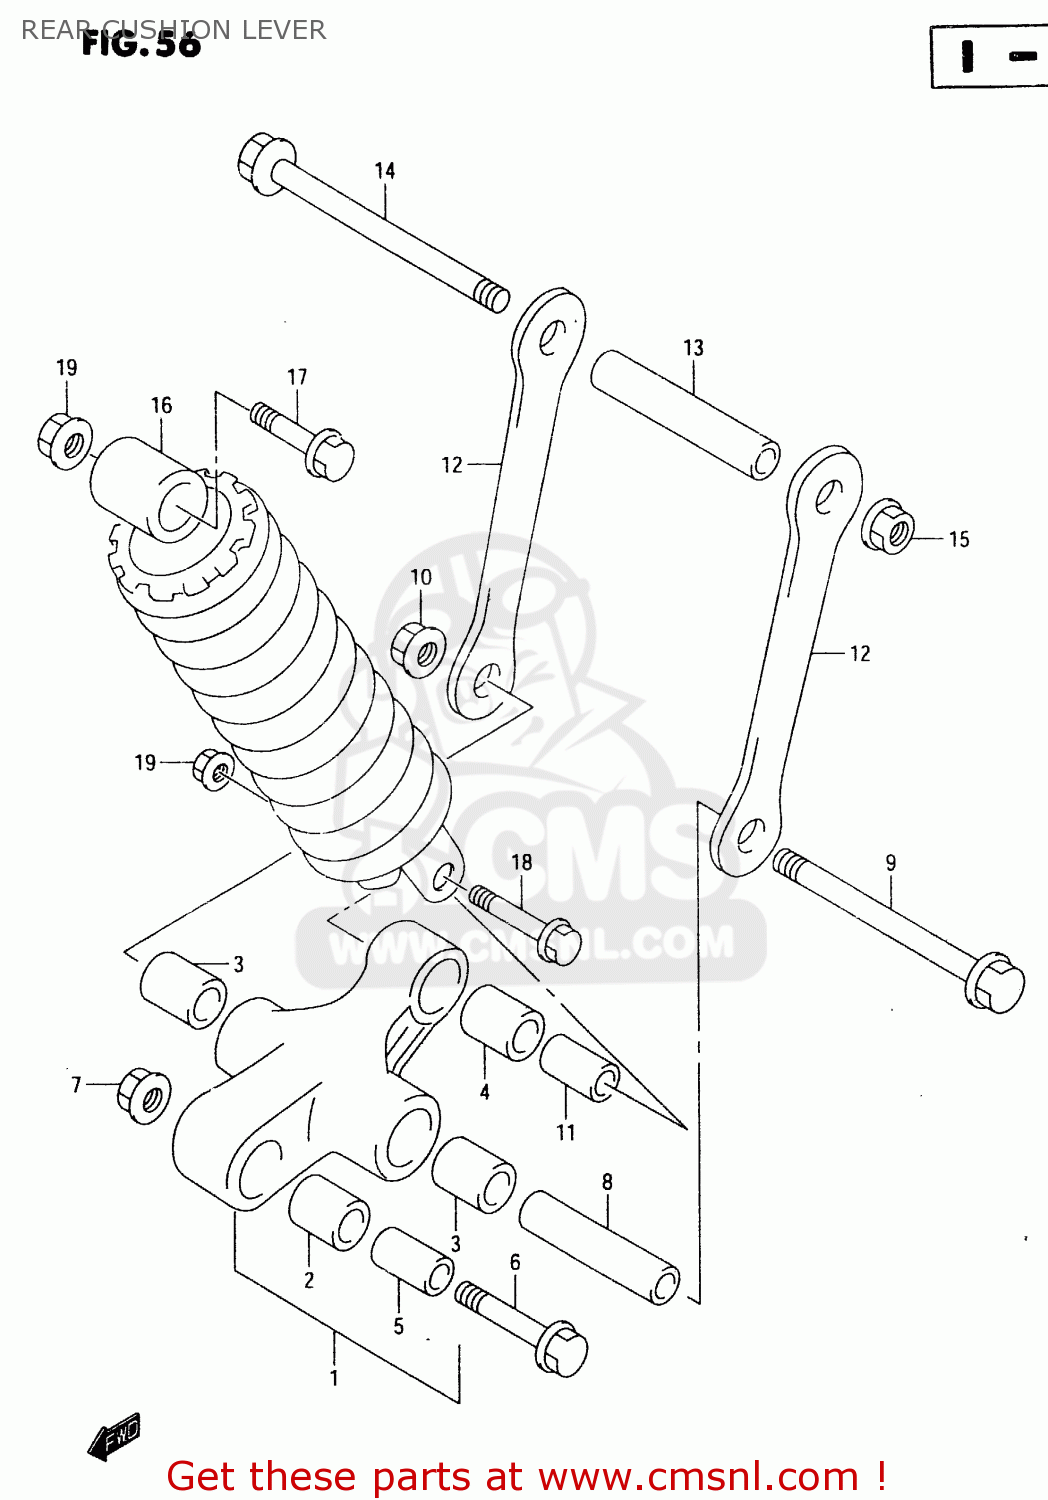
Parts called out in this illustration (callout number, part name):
1	LEVER SET,RR CUSHION
2	BEARING(20X27X32)
3	BEARING(20X27X23.5)
4	BEARING(17X24X26)
5	SPACER(14X20X34)
6	BOLT(14X66)
7	NUT
8	SPACER(14X20X99)
9	BOLT(14X129)
10	NUT
11	SPACER,RR CUSHION LEVER
12	ROD,RR CUSHION
13	SPACER(14X20X99)
14	BOLT(14X129)
15	NUT
16	ABSORBER ASSY,RR SHOCK
17	BOLT(10X50)
18	BOLT(10X54)
19	NUT
